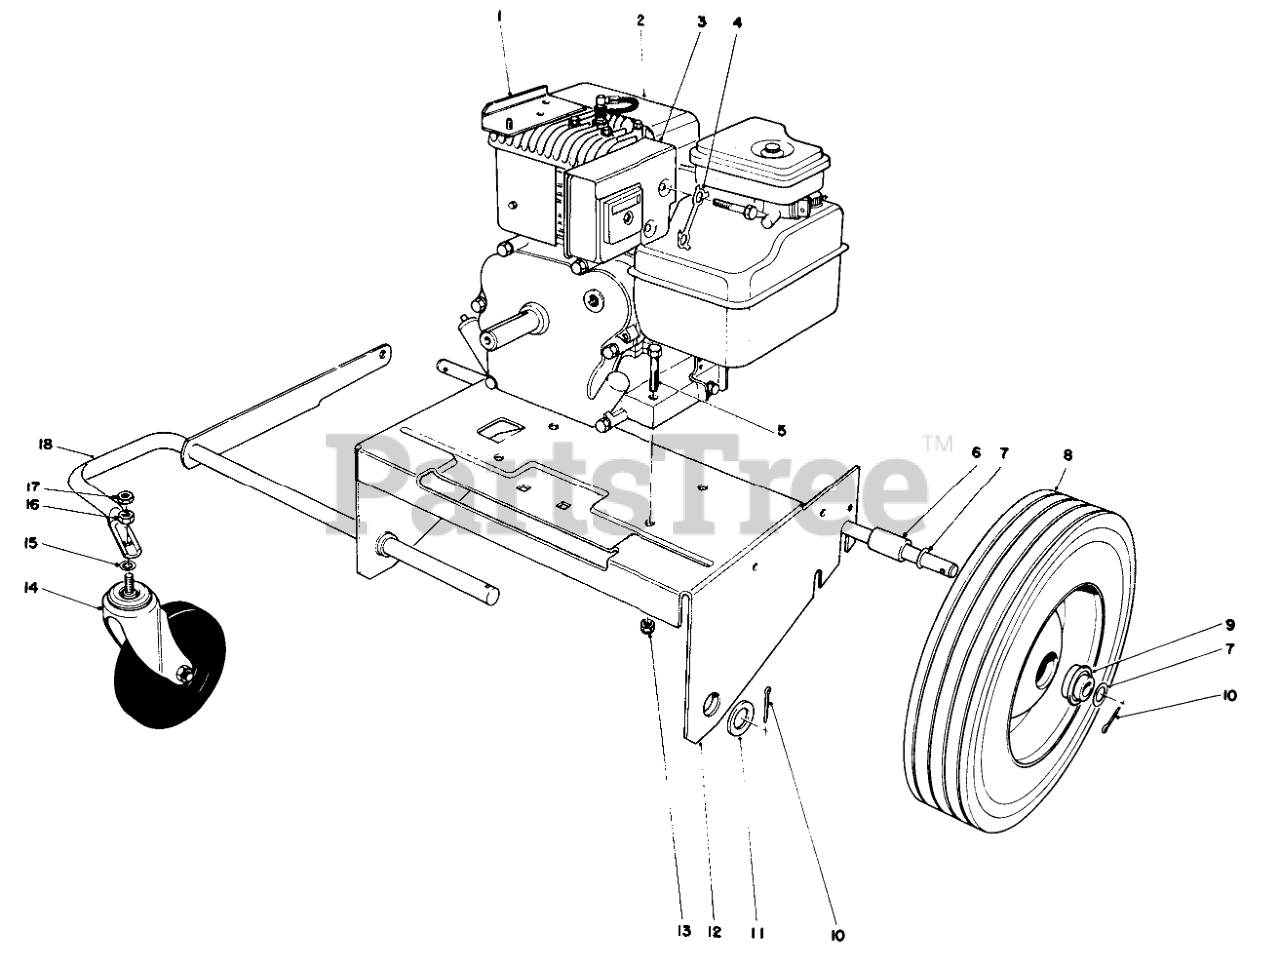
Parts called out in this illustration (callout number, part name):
1	MOUNTING BRKT WA
2	Engine
3	Heat Shield
4	Lock Strip
5	SCREW-HH
6	SPACER-AXLE
7	WASHER
8	Wheel (Incl. Ref. #9)
9	BEARING
10	PIN-COTTER
11	WASHER-FLAT
12	Engine Plate
13	NUT-LOCK, CONE
14	CASTER
15	WASHER-LOCK/INT
16	NUT-HH
17	1/2-13 CONELOCK NUT
18	Front Wheel Support
